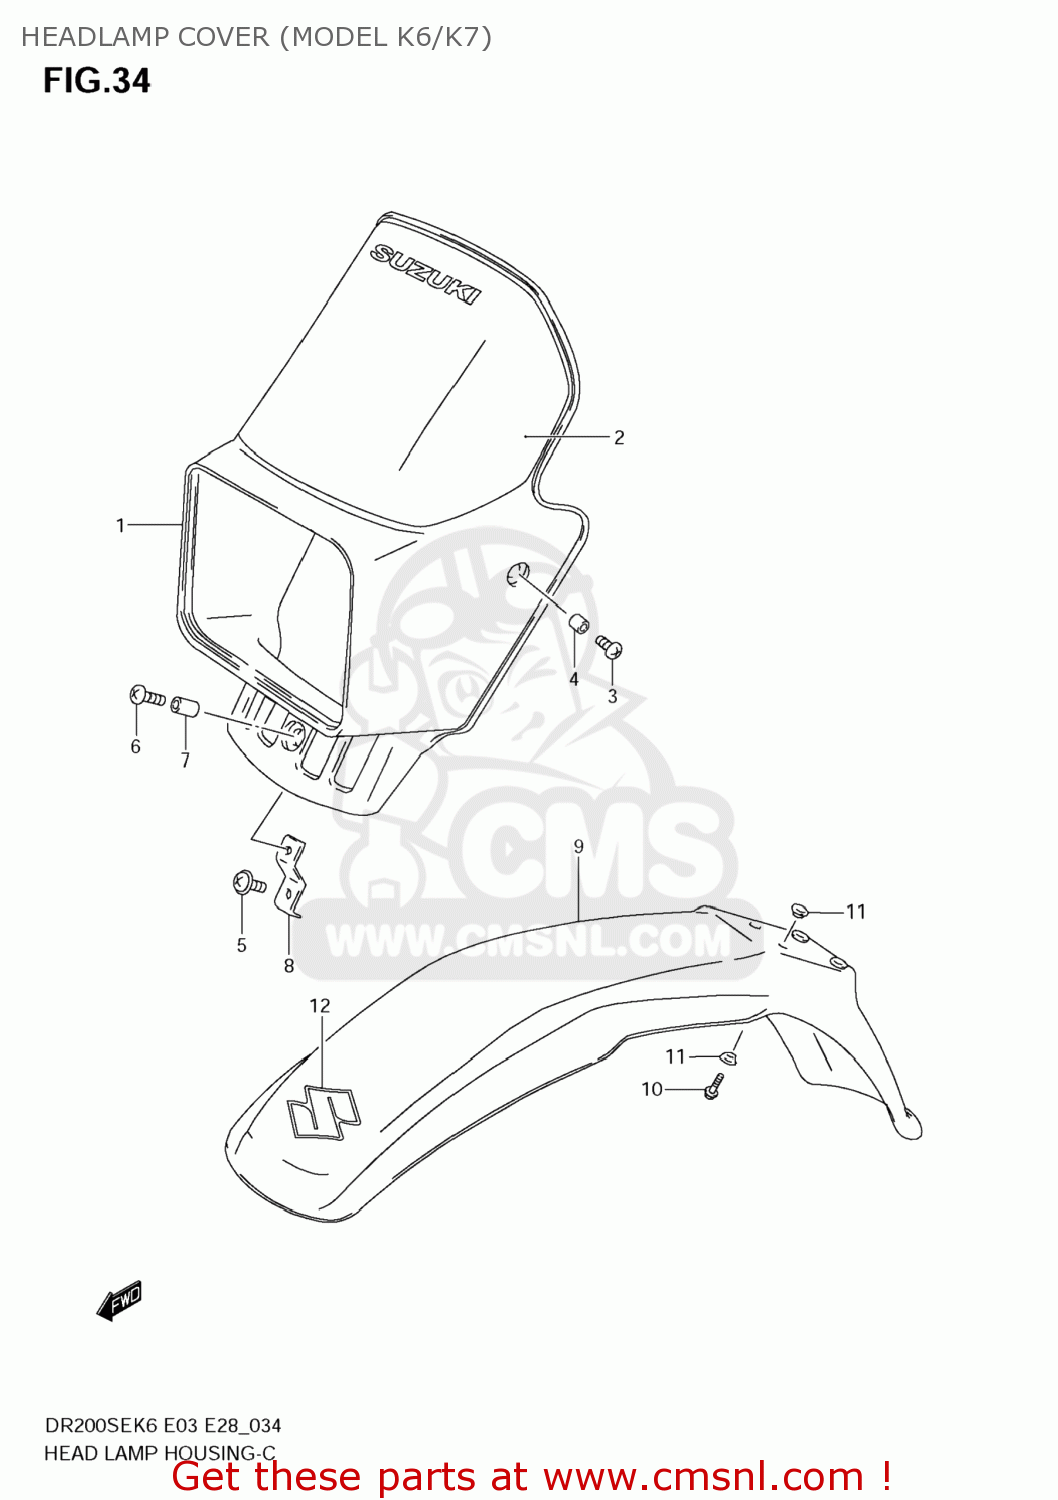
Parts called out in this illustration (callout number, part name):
1	COVER,HEADLAMP
2	TAPE,HEADLAMP COVER
3	SCREW
4	SPACER(6.1X8X3.5)
5	SCREW
6	SCREW
7	SPACER(6.1X8X12)
8	BRACE,HEADLAMP HOUSING LWR
9	FENDER,FR
10	BOLT
11	WASHER
12	EMBLEM,S
